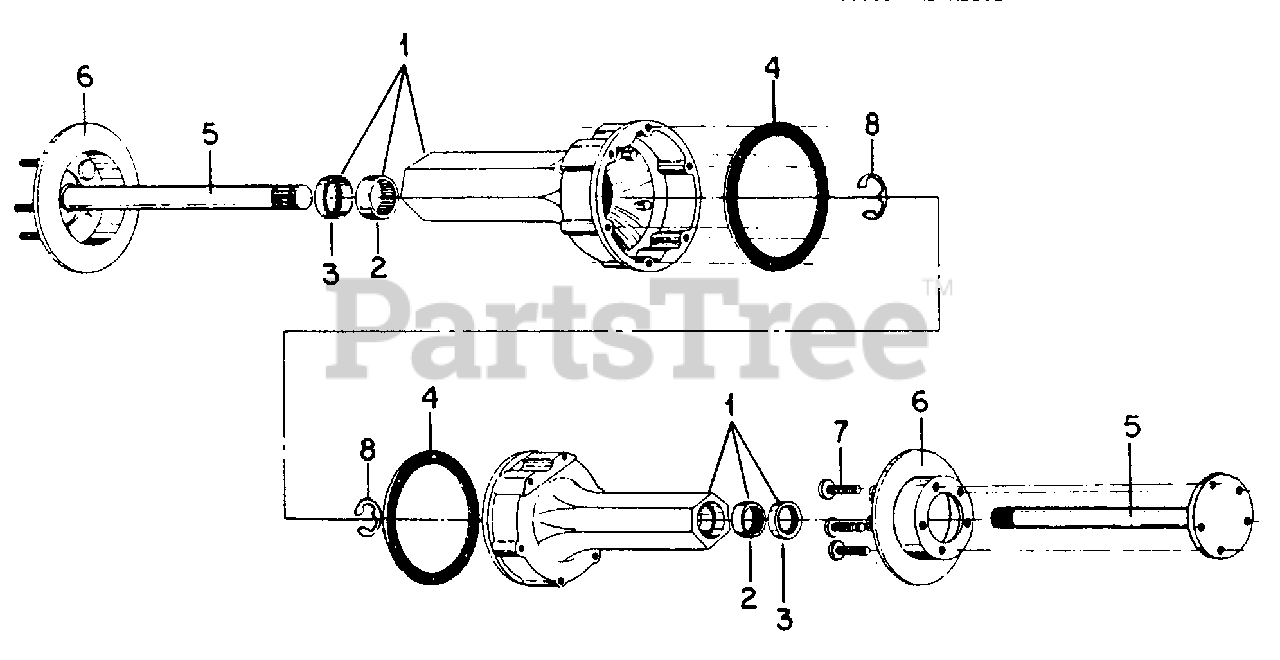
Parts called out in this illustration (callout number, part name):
1	Carrier Assy, Rear Axle
2	Bearing, Needle
3	Seal, Oil
4	Gasket, Carrier
5	Axle, Rear
6	Disc, Brake
7	Bolt, Lug
8	E-Ring, .668 Ext Ret
